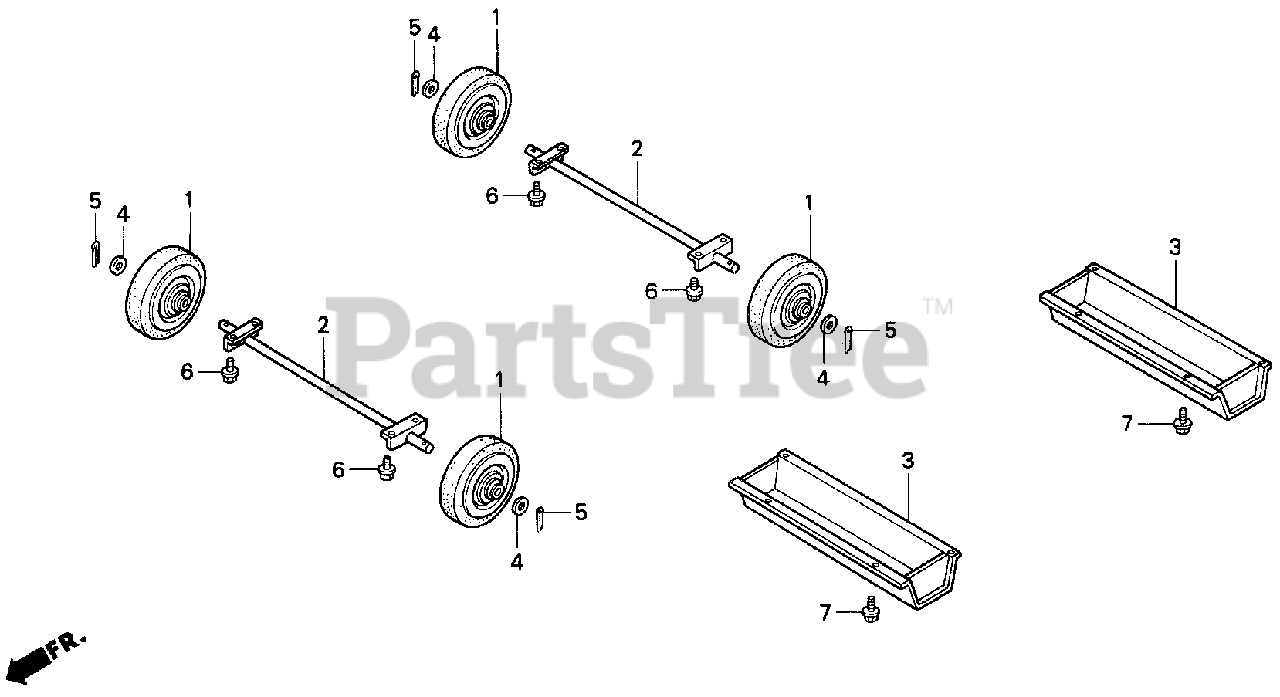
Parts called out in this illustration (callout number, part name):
2	SHAFT, WHEEL
3	STAND *NH105*
4	WASHER, FLAT (20MM)
5	PIN, COTTER (4.0X30)
6	BOLT, FLANGE (8X16)
7	BOLT, FLANGE (8X16)
